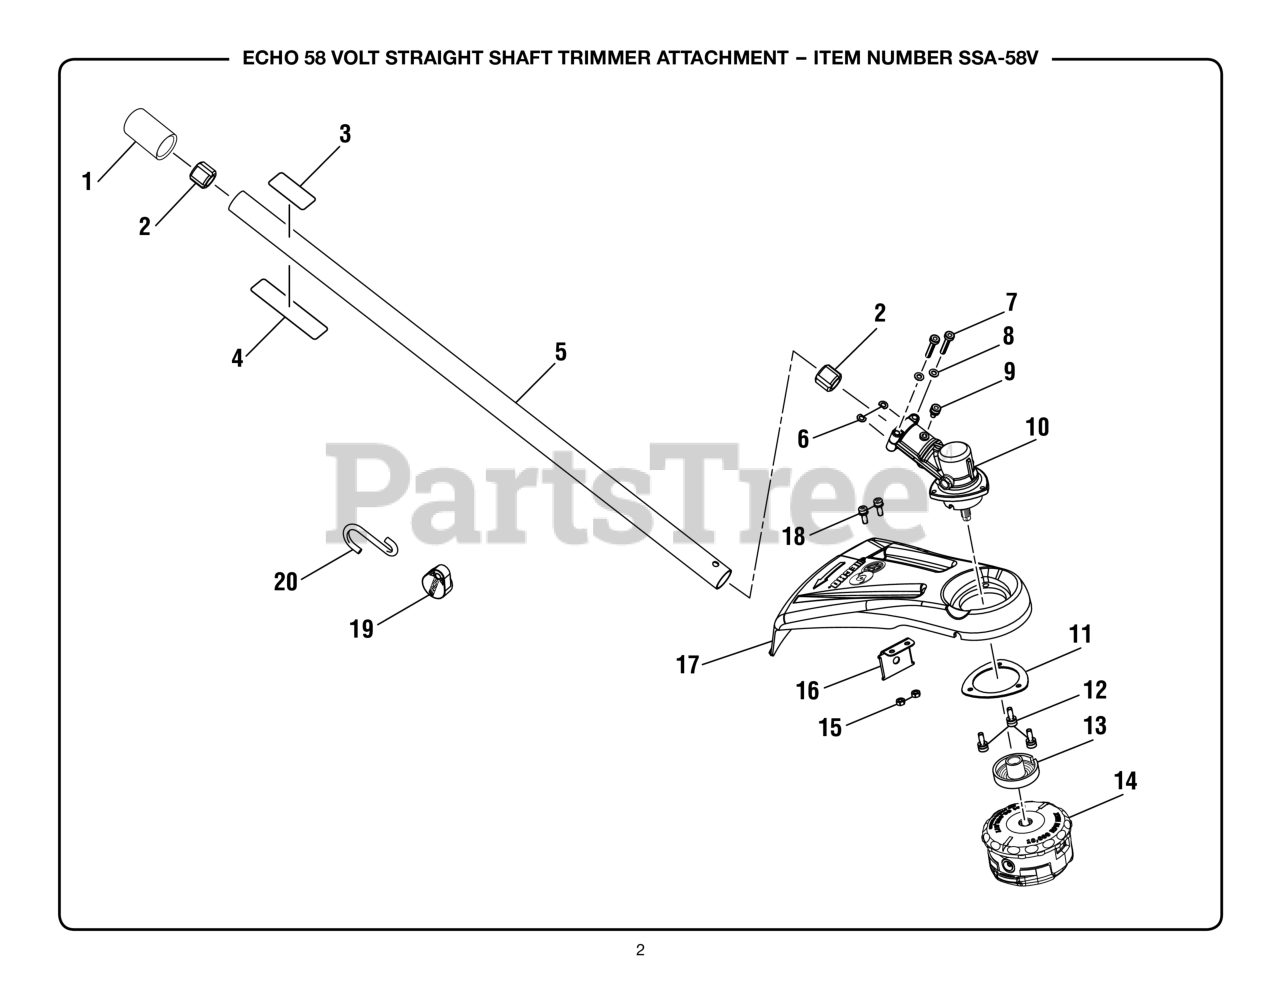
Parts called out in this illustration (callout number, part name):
1	End Cap
2	Rubber Spacer
3	Warning Icon Label
4	Data Label
5	Lower Boom Assembly
6	Washer (Special)
7	Screw (M5 x 26 mm, T25 Torx Pan Hd.)
8	Washer (ID5.2 x OD10 x 0.8t)
9	Screw w/Washers (M5 x 7 mm, T25 Torx Pan Hd.)
10	Gear Box
11	Fixed Plate
12	Screw w/Washers (M5 x 12.5 mm, T25 Torx Pan Hd.)
13	Flanged Washer
14	Stringhead Assembly
15	Hex Nut (M5)
16	Line Cutting Blade
17	Grass Deflector
18	Screw w/Washers (M5 x 12 mm, Pan Hd.)
19	Boom Cap
